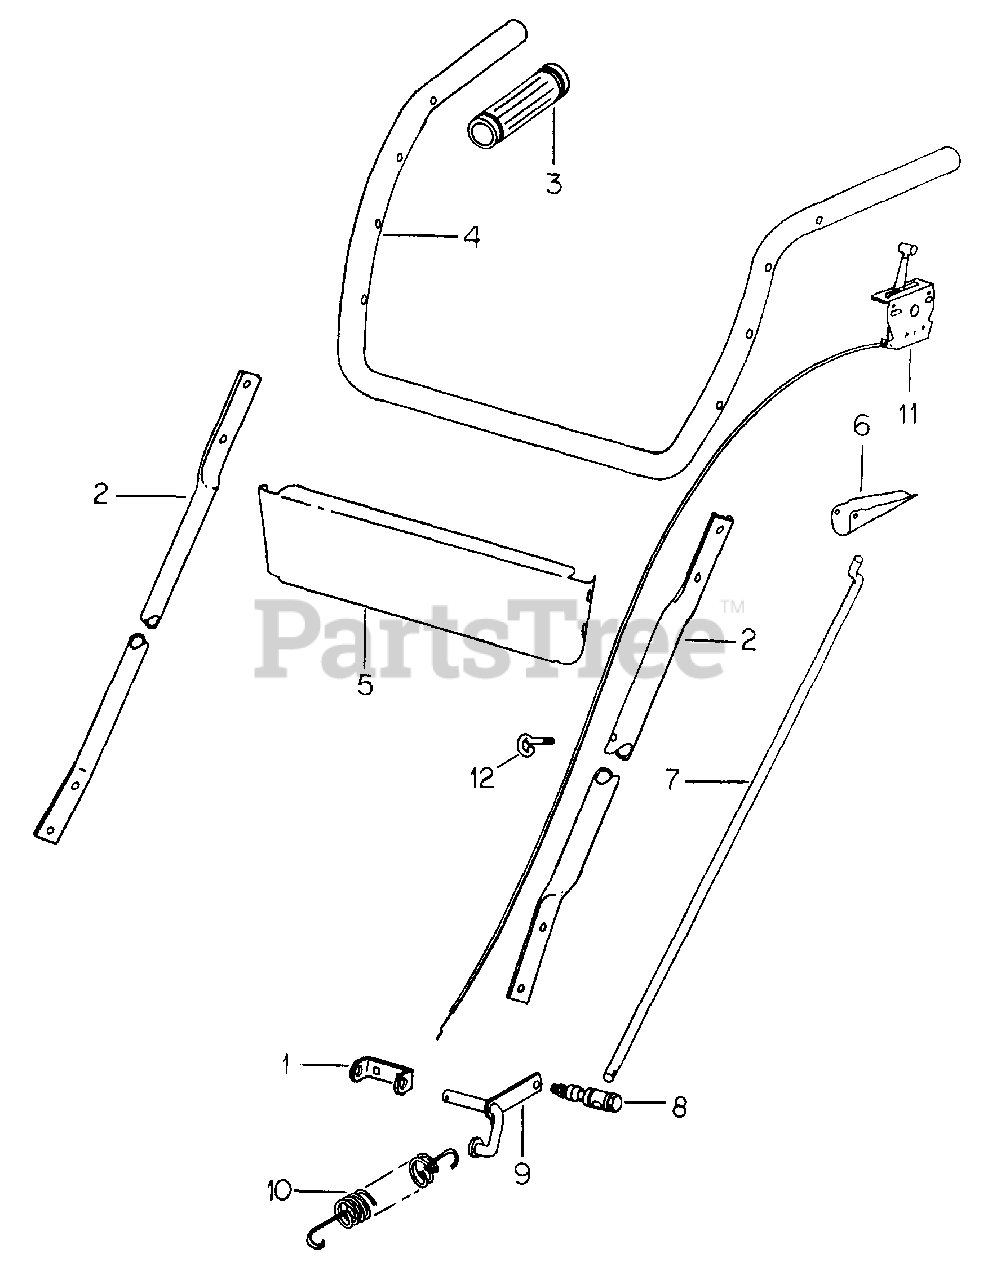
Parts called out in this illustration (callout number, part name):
1	BRACKET, PIVOT
2	EXTENSION, HANDLE BAR
3	GRIP, RUBBER HANDLE
5	PLATE, SUPPORT
6	HANDLE, CLUTCH
7	ROD, CLUTCH
7	ROD, CLUTCH ADJ
7	ROD, CLUTCH LONG
8	JOINT, BALL
9	LEVER, CLUTCH
10	SPRING, TENSION
11	CONTROL, THROTTLE
